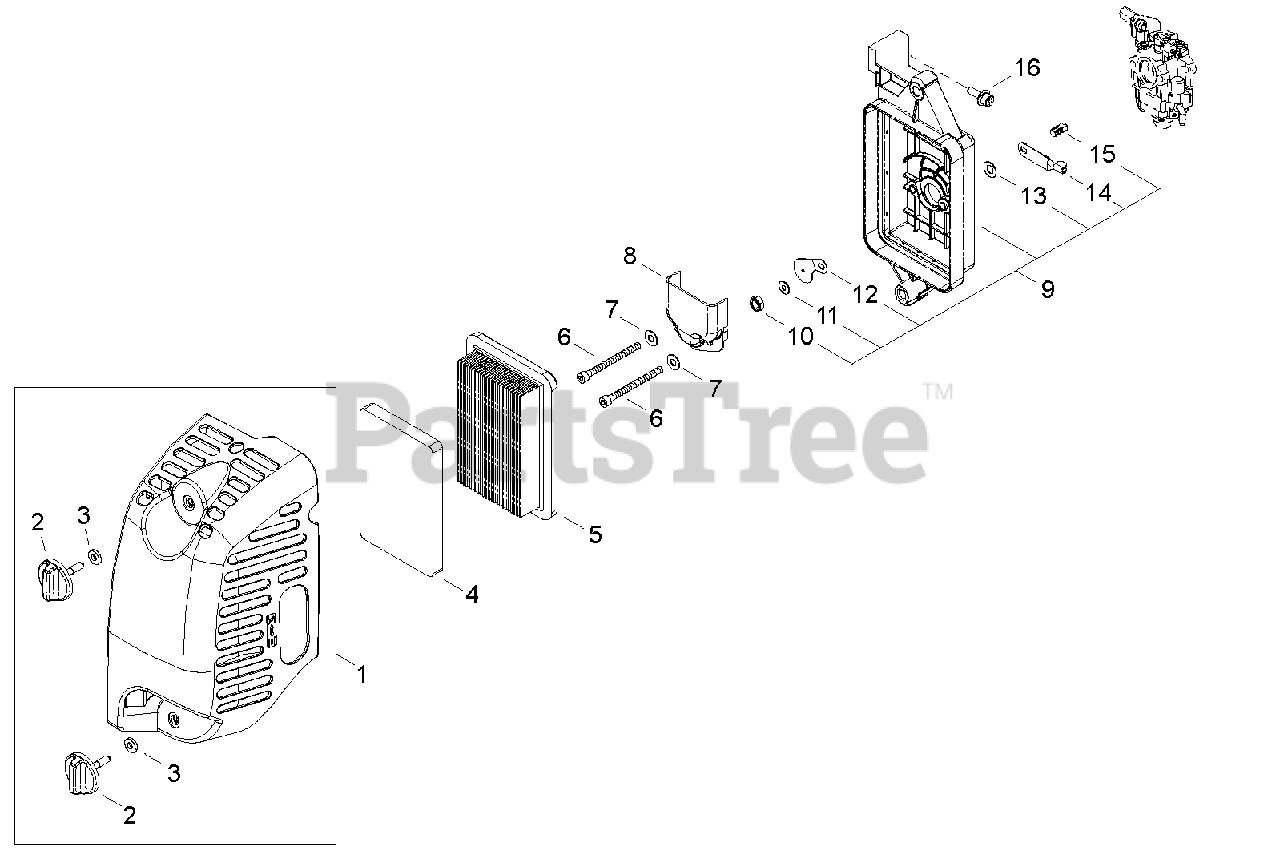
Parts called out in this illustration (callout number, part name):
1	AIR FILTER COVER ASSY
2	THUMBSCREW
3	WASHER - VYNYL
4	PRE-FILTER - FOAM
5	FILTER, AIR
6	SCREW - 5X70
7	WASHER - 5
8	DEFLECTOR PLATE
9	CASE, AIR FILTER
10	NUT - 6
11	LOCKWASHER - 6
12	PLATE, CHOKE
13	WASHER - CONICAL
14	LEVER, CHOKE
15	SHAFT, CHOKE
16	SCREW - 5X20
